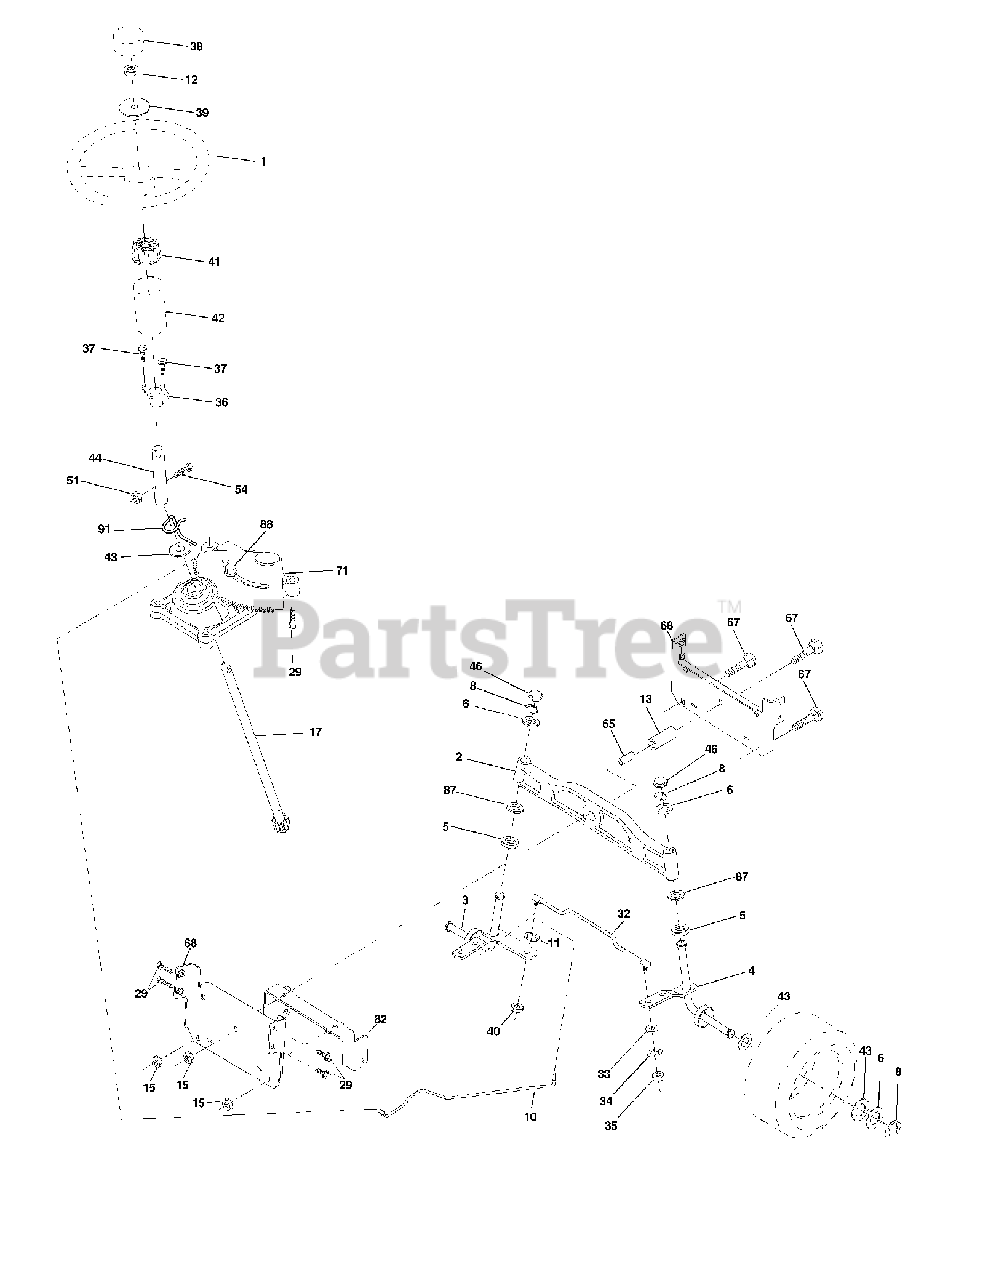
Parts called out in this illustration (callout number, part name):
1	STEERING WHEEL
2	AXLE ASM
3	SPINDLE.ASM.LH.15"TIRES
4	SPINDLE.ASM.RH.15"TIRES
8	RING CLIP
10	DRAGLINK.15".TIRES.2001
11	WASHER, LOCK 3/8
12	NUT.HEX.1/2-20
13	TUBE-PIVOT AXLE T
15	Flange Hex Lock Nut, 3/8-16
17	SHAFT ASM, STEERING
33	WASHER M
34	LOCKWASHER
35	NUT, CROWNLOCK
37	SCREW.TT.#10-32X.5.3/8.FLANGE
38	INSERT CAP STRG
41	STEERING WHEEL ADAPTOR
42	BOOT.STEERING.SHAFT.BLACK
44	EXT, STEERING SHAFT
46	CAP.SPINDLE.BLACK
51	NUT.CROWNLOCK.1/4-28
54	HEX BOLT
65	SPACER BRACE AXLE
68	BRACE.AXLE.15"TIRES
71	STEERING ASM
82	Chassis Suspension Bracket, Front 15
87	WASHER, FLAT .781 X 1 1/2"
88	BOLT, SHOULDER 7/16-20
91	CLIP.STEERING
